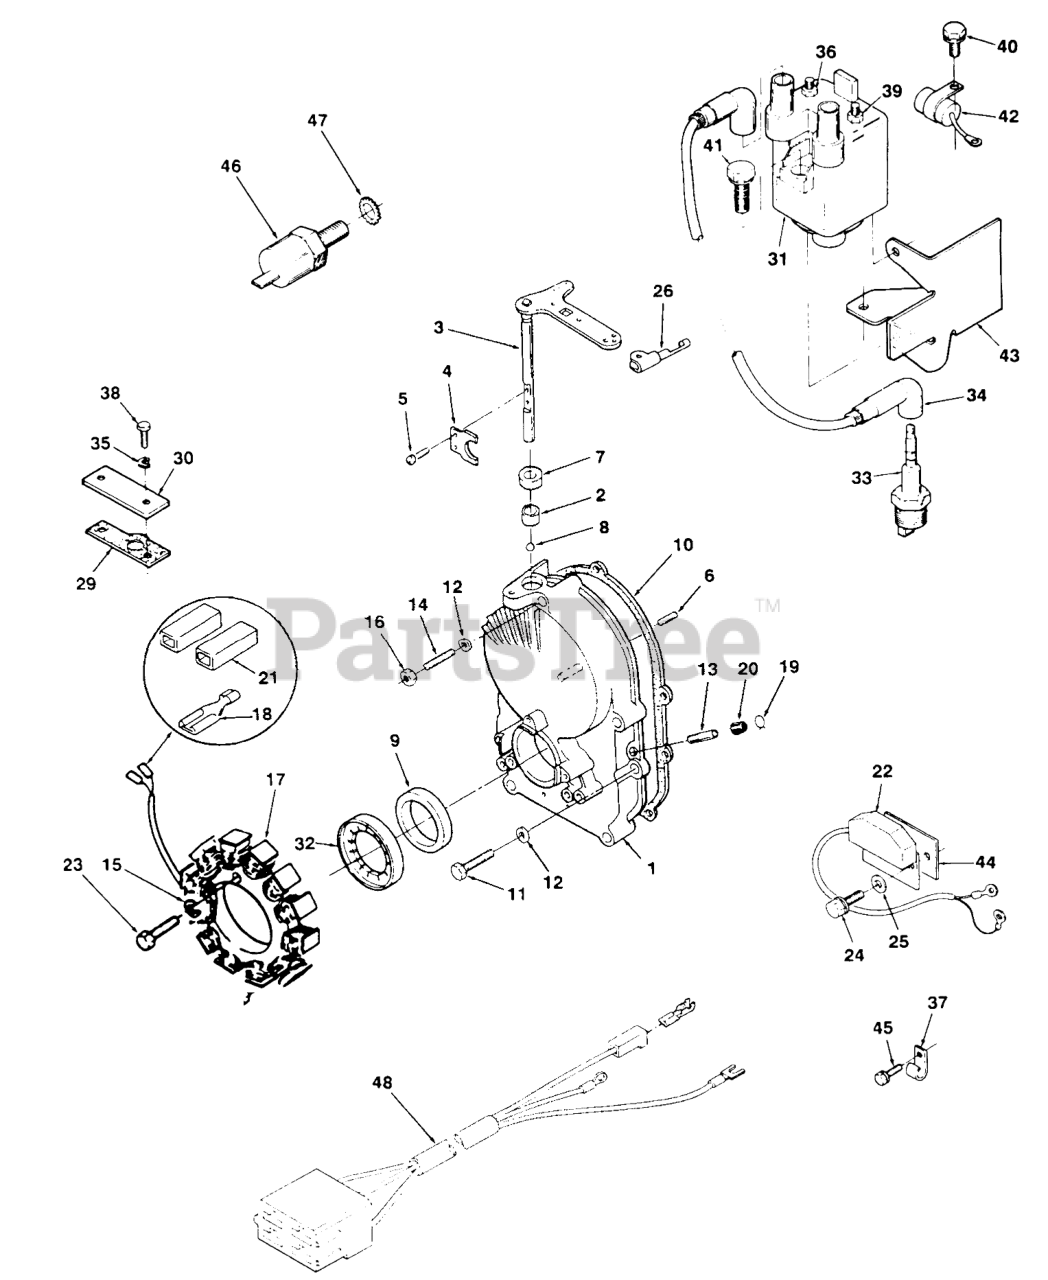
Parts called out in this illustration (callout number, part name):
1	Kit-Gearcase (Incl. Ref.#2 thru 9)
2	BEARING
3	SHAFT/ARM-GOVERNOR
5	SCREW-PAN HD
6	PIN-DOWEL
10	Gasket
11	HEX-HEAD CAP SCREW
12	WASHER
13	TUBE-PORT, VACUUM
14	STUD-GEAR COVER
15	WASHER-LOCK
16	NUT-GEAR COVER
17	KIT - STATOR
18	TERMINAL
19	CLAMP
20	CAP-FUEL OUTLET
21	BODY-TERM. CONNECTOR KIT
22	CONTROL-IGNITION
23	Screw-HH
24	Bolt
25	WASHER-LOCK
29	Gasket-Plate
30	PLATE-COVER
31	COIL-BATTERY IGNITION
32	ROTOR-IGNITION
33	SPARK PLUG
34	Wire-Plug
35	WASHER-FLAT
36	NUT-HEX FLANGE
37	CLIP-WIRE
38	SCREW - CAP HEX HEAD
39	NUT-HEX FLANGE
40	HEX HD CAPSCREW
41	SCREW-HH
42	CONDENSER
43	BRACKET - COIL MTG
44	INSULATOR-IGN MODULE
45	HEX-HEAD CAP SCREW
46	HIGH TEMPERATURE
47	WASHER-LOCK EXT TO
48	WIRE HARNESS
